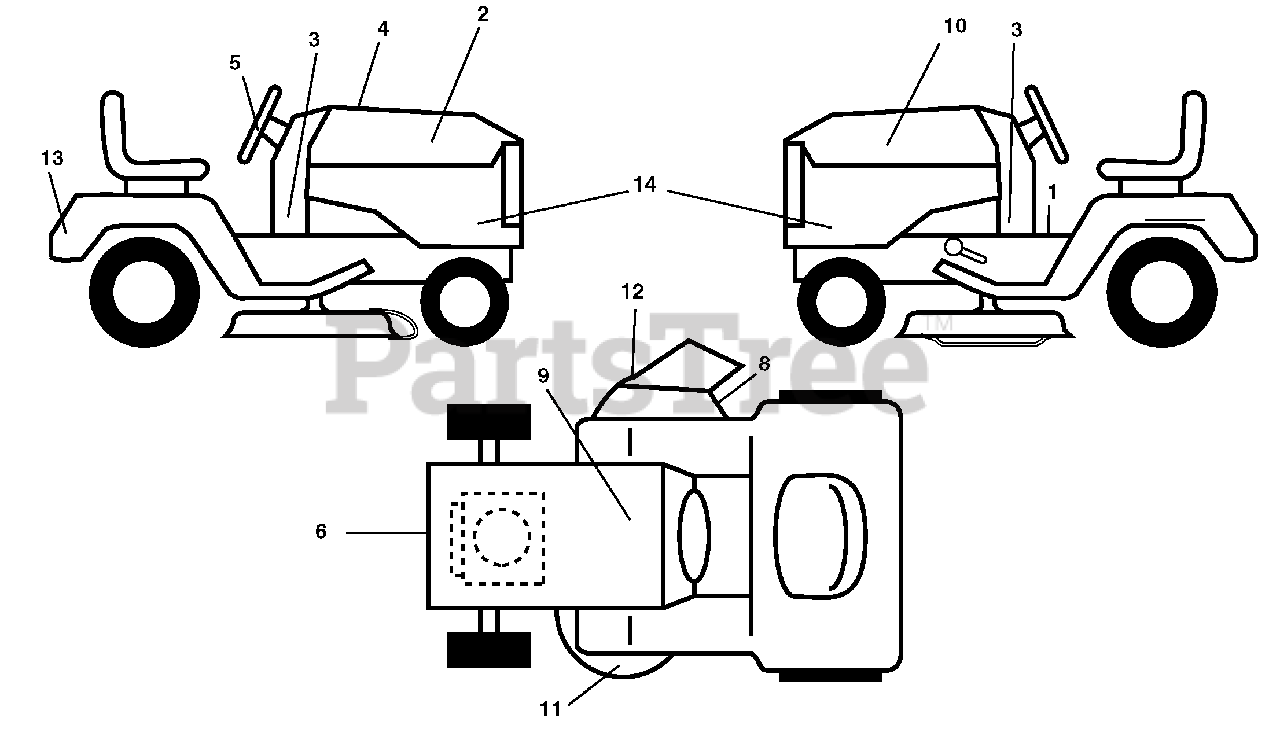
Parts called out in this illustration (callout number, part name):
1	Decal, Operator's
2	Decal, Hood RH
3	Decal, Dash Lower
4	Decal, Replacement
5	Decal, Strg Whl
6	Decal, Engine HP
8	Decal, Mower Sch.
9	Decal, Battery Dnge/Poi
10	Decal, Hood LH
11	Decal, Mower Caution
12	Decal, Mower Warning Keep Hand Away
13	Decal, Fender
14	Decal, Panel SD
14	Decal, Bypass
14	Pad, Footrest, LH
14	Pad, Footrest, RH
14	Manual, Operator's (Eng & French)
14	Manual, Parts
